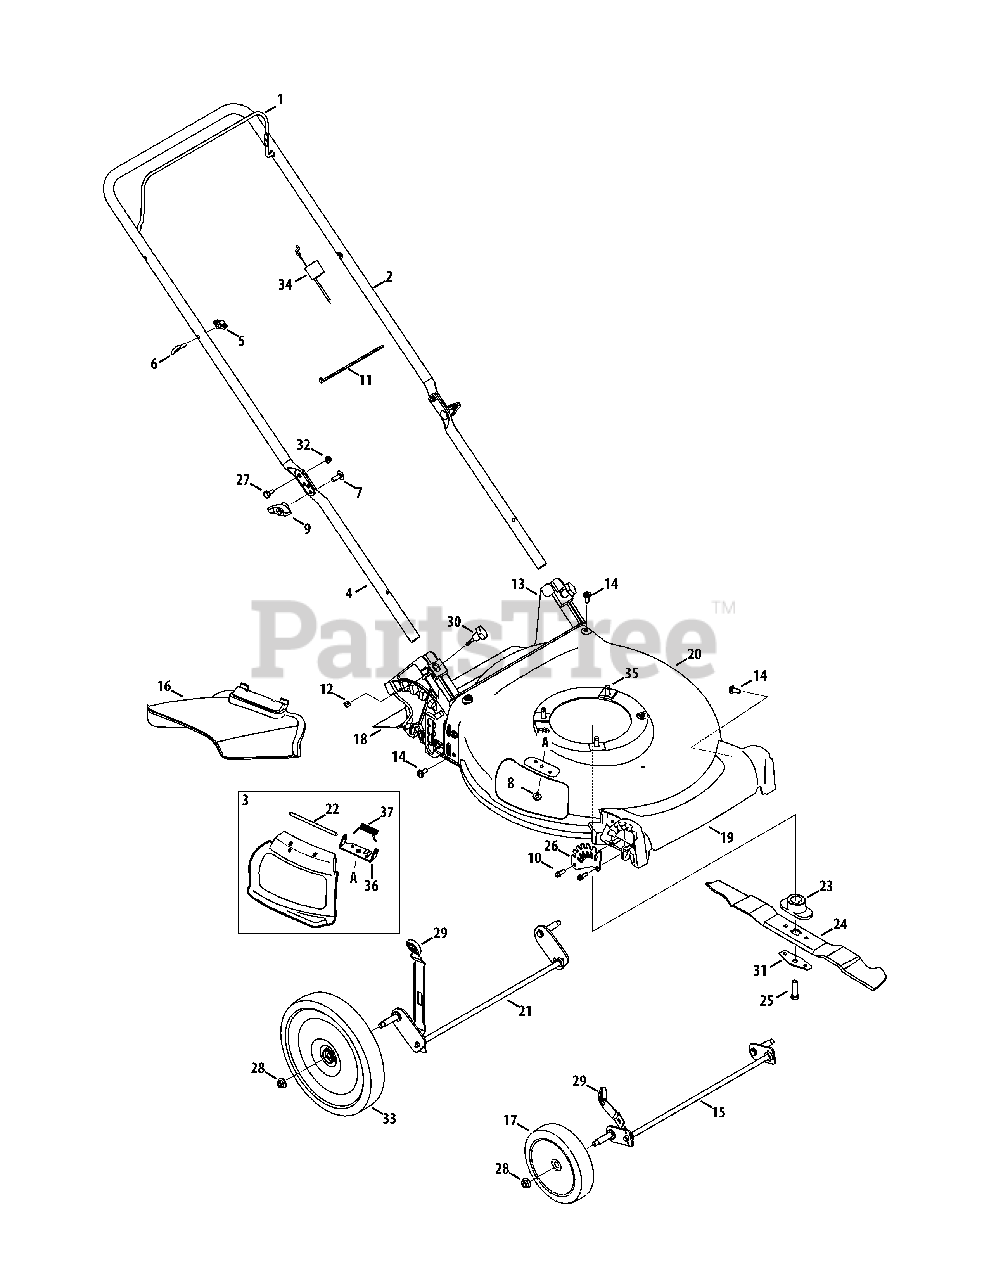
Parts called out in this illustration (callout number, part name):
1	Blade Control
2	Upper Handle
3	Hinged Mulch Plug Assembly
4	Lower Handle
5	Wing Nut
6	Rope Guide
7	Carriage Screw ,5/16-18
8	Screw, 1/4-20 x .500
9	Wing Knob
10	Screw, 1/4-15 x .750
11	Cable Tie
12	Nut, Sq., 1/4-20
13	Rear Baffle
14	Screw, 5/16-14 x .750
15	Front Axle Assembly
16	Side Chute
17	Front Wheel, 7 x 1.8, Gray
18	Trail Shield
19	Front Cover
20	Deck - 21"
21	Rear Axle Assembly
22	Hinge Pin
23	Blade Adapter
24	Mulching Blade
25	Screw , 3/8-24 x 1.50
26	Front Height Adjuster Plate
27	Sldr. Screw, .375 x .126 x 1/4-20
28	Flange Lock Nut, 3/8-16
29	Adjustment Lever Knob
30	Wing Nut
31	Blade Bell Support
32	Nut, Flange Lock, 1/4-20
33	Rear Wheel, 11 x 1.8, Gray
34	Control Cable, 37.25" (Briggs)
34	Control Cable, 61.15" (MTD OHV)
35	TT Sems Screw, 3/8-16 x 1.0
36	Chute Deflector Bracket
37	Torsion Spring
